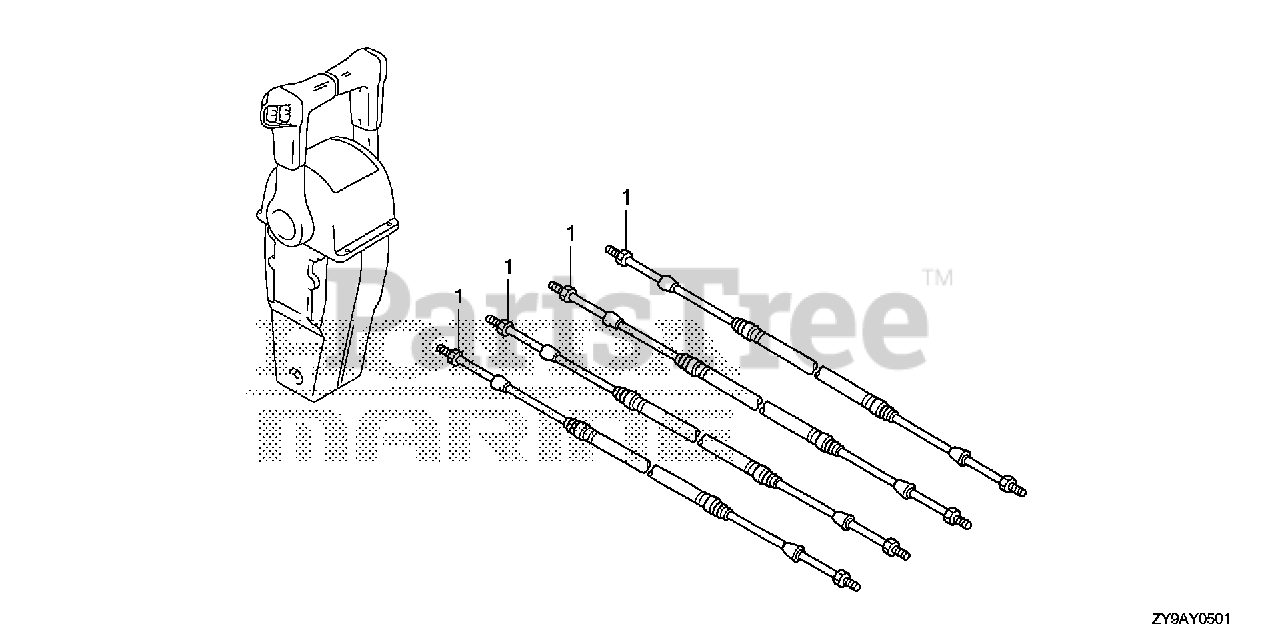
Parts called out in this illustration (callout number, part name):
1	CABLE, REMOTE CONTROL (10'') (LOW FRICTION)
1	CABLE ASSY., PUSH-PULL (33C-5FT)
1	CABLE, REMOTE CONTROL (11'') (LOW FRICTION)
1	CABLE ASSY., PUSH-PULL (33C-6FT)
1	CABLE, REMOTE CONTROL (12'') (LOW FRICTION)
1	CABLE ASSY., PUSH-PULL (33C-7FT)
1	CABLE, REMOTE CONTROL (13'') (LOW FRICTION)
1	CABLE ASSY., PUSH-PULL (33C-8FT)
1	CABLE, REMOTE CONTROL (14'') (LOW FRICTION)
1	CABLE ASSY., PUSH-PULL (33C-9F T)
1	CABLE, REMOTE CONTROL (15'') (LOW FRICTION)
1	CABLE ASSY., PUSH-PULL (33C-10FT)
1	CABLE, REMOTE CONTROL (16'') (LOW FRICTION) (NOT AVAILABLE)
1	CABLE ASSY., PUSH-PULL (33C-11FT)
1	CABLE, REMOTE CONTROL (17'') (LOW FRICTION)
1	CABLE ASSY., PUSH-PULL (33C-12 FT)
1	CABLE, REMOTE CONTROL (18') (LOW FRICTION) (NOT AVAILABLE)
1	CABLE ASSY., PUSH-PULL (33C-13 FT)
1	CABLE, REMOTE CONTROL (1 9'') (LOW FRICTION)
1	CABLE ASSY., PUSH-PULL (33C-14FT)
1	CABLE, REMOTE CONTROL (20'') (LOW FRICTION) (NOT AVAILABLE)
1	CABLE ASSY., PUSH-PULL (33C-15 FT)
1	CABLE, REMOTE CONTROL (21') (LOW FRICTION)
1	CABLE ASSY., PUSH-PULL (33C-16FT)
1	CABLE, REMOTE CONTROL (22') (LOW FRICTION) (NOT AVAILABLE)
1	CABLE ASSY., PUSH-PULL (33C-17 FT)
1	CABLE, REMOTE CONTROL (2 3'') (LOW FRICTION)
1	CABLE ASSY., PUSH-PULL (33C-18 FT)
1	CABLE, REMOTE CONTROL (24') (LOW FRICTION) (NOT AVAILABLE)
1	CABLE ASSY., PUSH-PULL (33C-19FT)
1	CABLE, REMOTE CONTROL (25') (LOW FRICTION)
1	CABLE ASSY., PUSH-PULL (33C-20FT)
1	CABLE, REMOTE CONTROL (26') (LOW FRICTION)
1	CABLE ASSY., PUSH-PULL (33C-21FT)
1	CABLE, REMOTE CONTROL (27') (LOW FRICTION)
1	CABLE ASSY., PUSH-PULL (33C-22FT)
1	CABLE, REMOTE CONTROL (28') (LOW FRICTION) (NOT AVAILABLE)
1	CABLE ASSY., PUSH-PULL (33C-23FT)
1	CABLE, REMOTE CONTROL (2 9') (LOW FRICTION)
1	CABLE ASSY., PUSH-PULL (33C-24FT)
1	CABLE, REMOTE CONTROL (30') (LOW FRICTION) (NOT AVAILABLE)
1	CABLE ASSY., PUSH-PULL (33C-25FT)
1	CABLE, REMOTE CONTROL (31') (LOW FRICTION)
1	CABLE ASSY., PUSH-PULL (33C-26FT)
1	CABLE, REMOTE CONTROL (32') (LOW FRICTION) (NOT AVAILABLE)
1	CABLE ASSY., PUSH-PULL (33C-27FT)
1	CABLE, REMOTE CONTROL (33') (LOW FRICTION)
1	CABLE ASSY., PUSH-PULL (33C-28FT)
1	CABLE, REMOTE CONTROL (34') (LOW FRICTION)
1	CABLE ASSY., PUSH-PULL (33C-29FT)
1	CABLE, REMOTE CONTROL (35') (LOW FRICTION)
1	CABLE ASSY., PUSH-PULL (33C-30FT)
1	CABLE ASSY., PUSH-PULL (33C-31FT)
1	CABLE ASSY., PUSH-PULL (33C-32FT)
